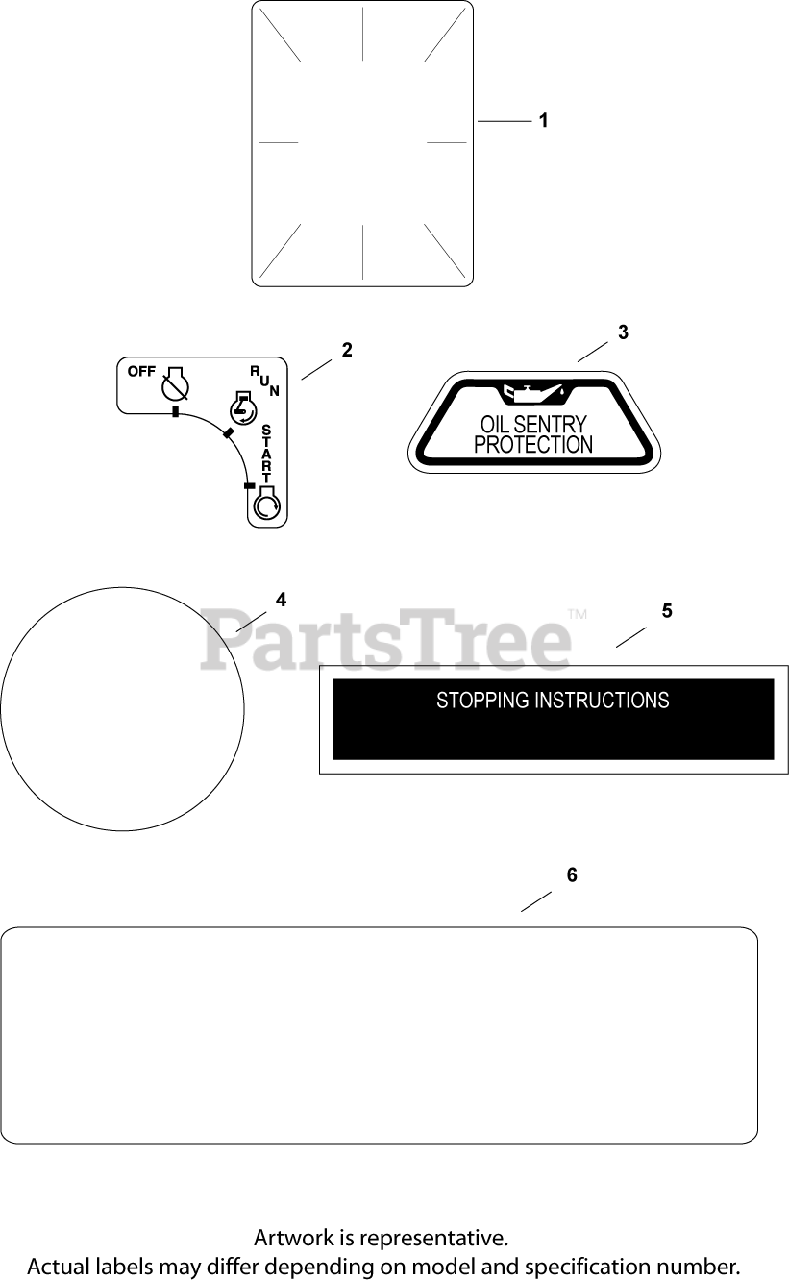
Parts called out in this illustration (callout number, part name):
1	DECAL, CLEAR LAMINATE USE 25 113 70-S
2	DECAL, KEY SWITCH
3	DECAL, OIL SENTRY - (#DSC)
4	LABEL, (ROUND KOHLER GOLD)-USE 24 113 18
5	DECAL, STOPPING INSTRUCTION
6	DECAL, 23 HP - (#24113216S)
